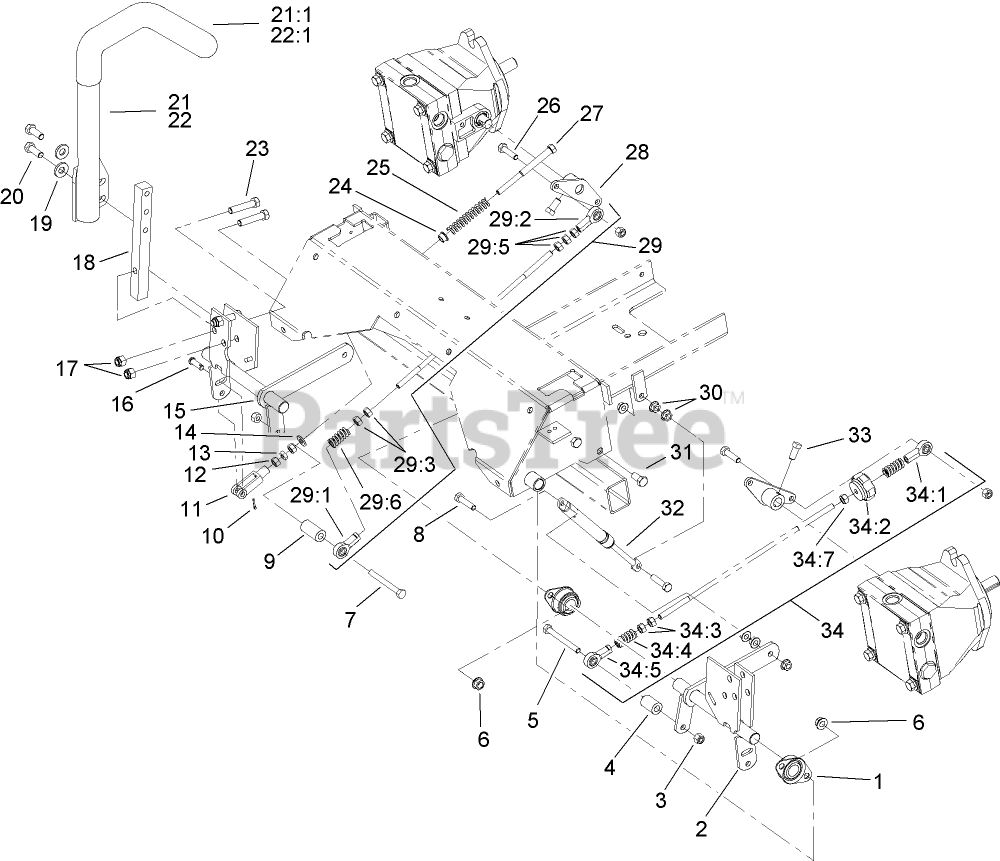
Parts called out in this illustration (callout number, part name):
1	BEARING-FLANGE, SIDE
2	CONTROL-MOTION, LH
3	NUT-LOCK, NI
4	SPACER-HYDRO CONTROL, LH
5	SCREW-HH
6	NUT-HHF, WHIZ
7	SCREW-HH
8	SCREW-HH
9	SPACER-CONTROL, HYD
10	PIN-COTTER
11	YOKE-ADJUSTABLE
12	NUT-HEX
13	NUT-JAM
14	WASHER-FLAT
15	CONTROL-MOTION, RH
16	PIN-CLEVIS
17	NUT-LOCK, NI
18	ARM-SHAFT, CONTROL
19	WASHER-BELLEVILLE
20	SCREW-HH
21	RH LEVER ASM
21:1	Grip-Control, Motion
22	LH LEVER ASM
22:1	Grip-Control, Motion
23	SCREW-HH
24	BUSHING-FLANGED
25	SPRING-RETURN, NEUTRAL
26	SCREW-HH
27	BOLT-RETURN, NEUTRAL
28	ARM-CONTROL, HYDRO
29	RH HYD CONNECT LINK ASM
29:1	BALLJOINT-RH
29:2	BALLJOINT-LH
29:5	NUT-HEX
29:6	SPRING-COMPRESSION
30	NUT-HF
31	SCREW-HH
32	DAMPER-CONTROL, MOTION
33	SCREW-SET
34	TRACKING ROD ASM
34:1	BALLJOINT-RH
34:2	KNOB-TRACKING
34:4	SPRING-COMPRESSION
34:5	BALLJOINT-LH
34:7	NUT-HEX
